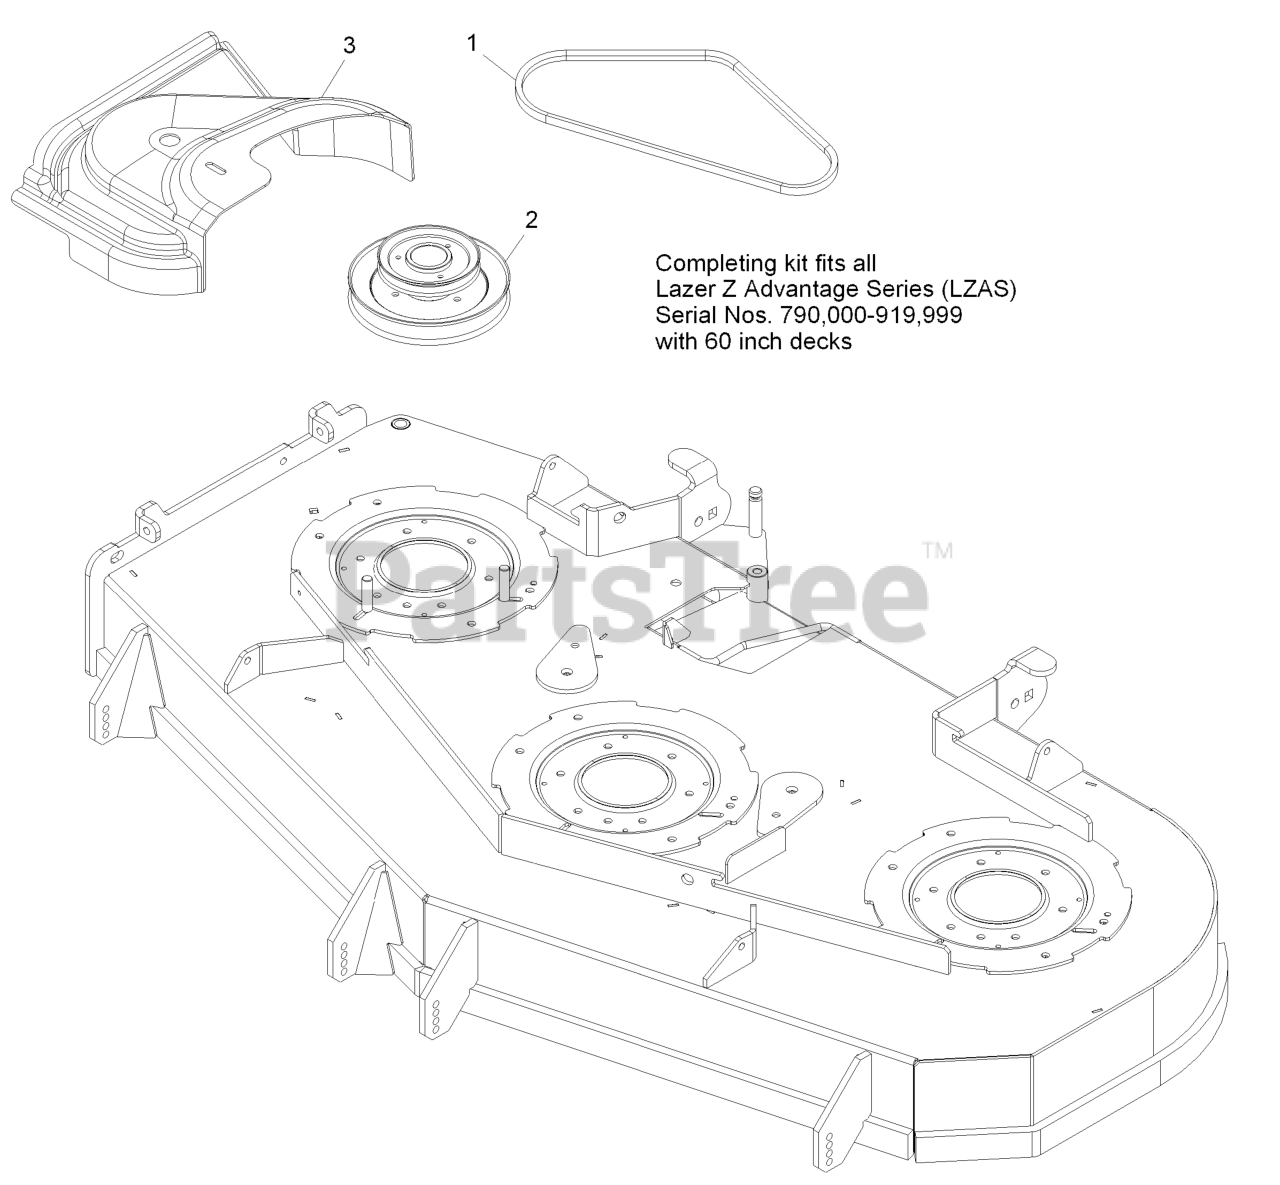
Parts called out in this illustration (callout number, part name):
1	BELT, BLOWER DRIVE 60
2	JACKSHAFT,UV DRIVE 604
3	COVER,BELT UV 60
